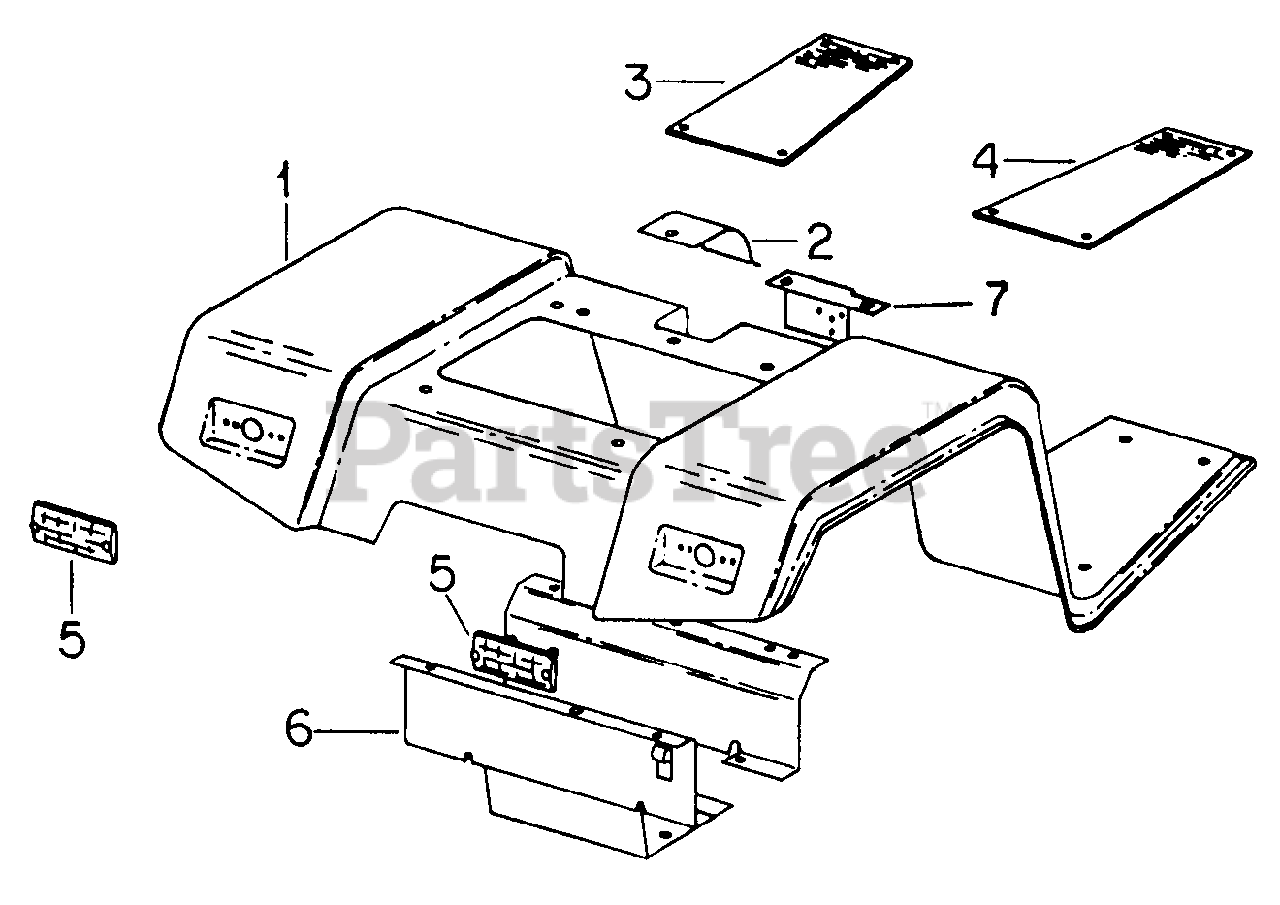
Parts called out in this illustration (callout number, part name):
2	Cover, Hydro Center
3	Tread, Platform, LH
4	Tread, Platform, RH
5	Reflector, Red
6	Support Assy, Fender
7	Bracket, Switch
